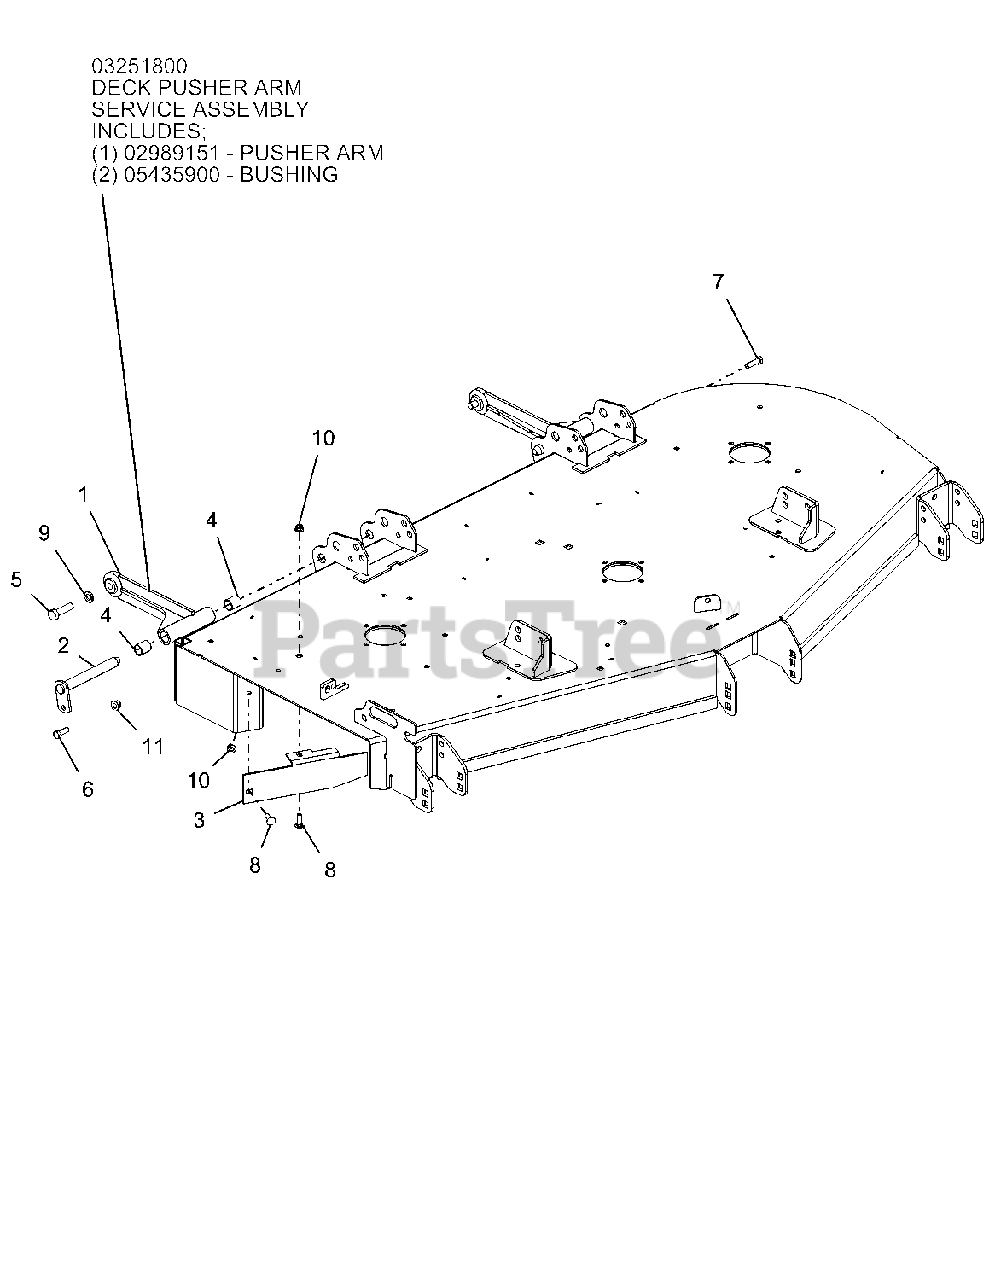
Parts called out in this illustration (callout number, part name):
1	DECK PUSHER ARM WLDMT - BLK
1	DECK PUSHER ARM SERVICE ASSEMBLY
1	PUSHER ARM
1	BUSHING
2	WLDMT, MOWER MTG. PIN
3	BAFFLE, DISCHARGE, 60"-RED
4	BRG, .750 X .875 X 1.000
5	BLT-HEX .50-13X1.75 G5 YZ EP80
6	BLT-HEX .38-16X1.00 GR5 YWZC
7	BLT-HEX .38-16X1.25 GR5 YWZC
8	BLT-RDHDSQSHNK .31-18X1.00 G5 Y
9	WSHR-LK .50X.125 REG YWZC
10	NUT-LK-NYL-FLG .31-18 YWZC
11	NUT-LK-NYL-FLG .38-16 YWZC
